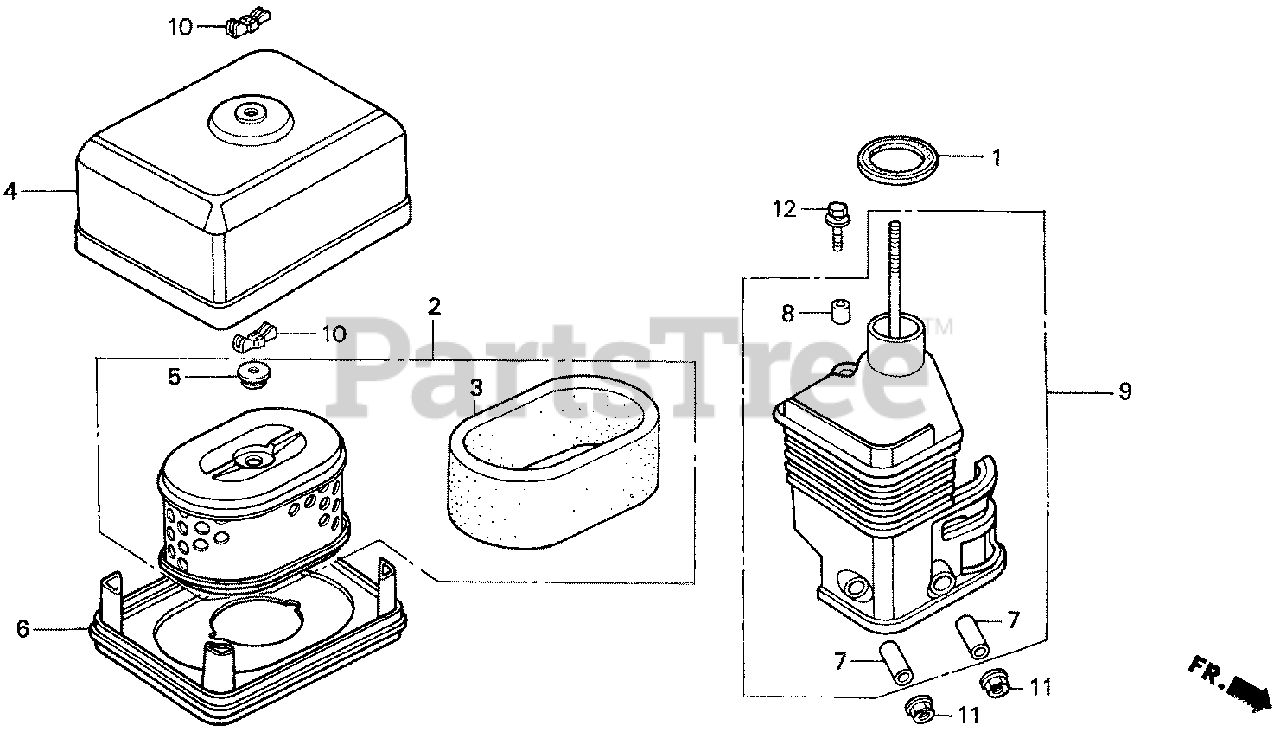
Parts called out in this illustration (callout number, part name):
1	GASKET, ELBOW
2	ELEMENT, AIR CLEANER (DUAL)
3	FILTER (OUTER)
4	COVER, AIR CLEANER (DUAL)
5	GROMMET, AIR CLEANER
6	NOSE, MUFFLER
7	COLLAR, AIR CLEANER
8	COLLAR B, AIR CLEANER
9	ELBOW, AIR CLEANER
10	WINGNUT, TOOL BOX SETTING
11	NUT, FLANGE (6MM)
12	BOLT, FLANGE (6X20)
